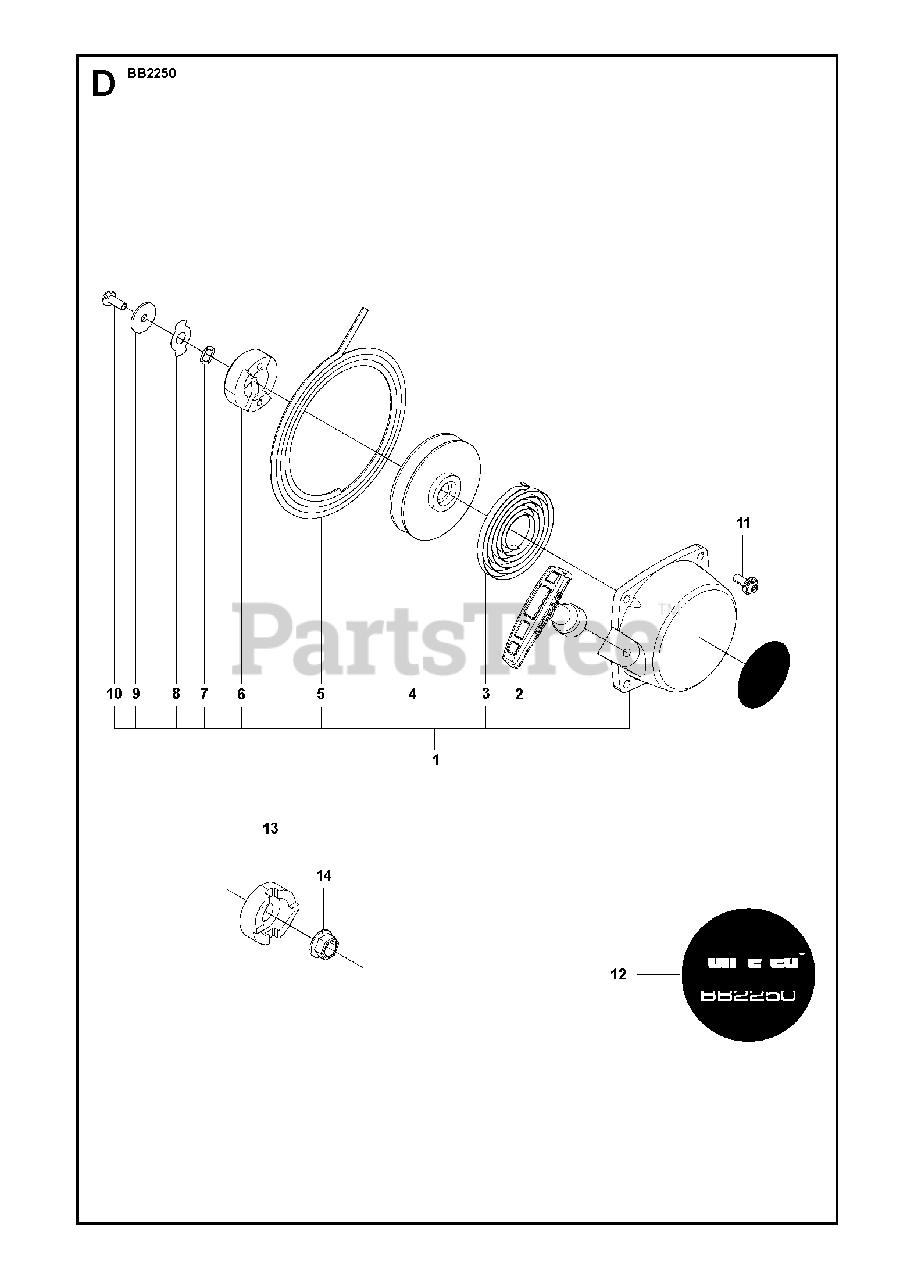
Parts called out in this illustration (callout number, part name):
1	STARTER ASSY
2	KNOB
3	SPRING
4	STARTER PULLEY
5	CHORD
6	STARTER PAWL
7	WASHER
8	RETAINER
9	WASHER
10	SCREW
13	PULLEY (RPLS 148775210)
14	NUT
